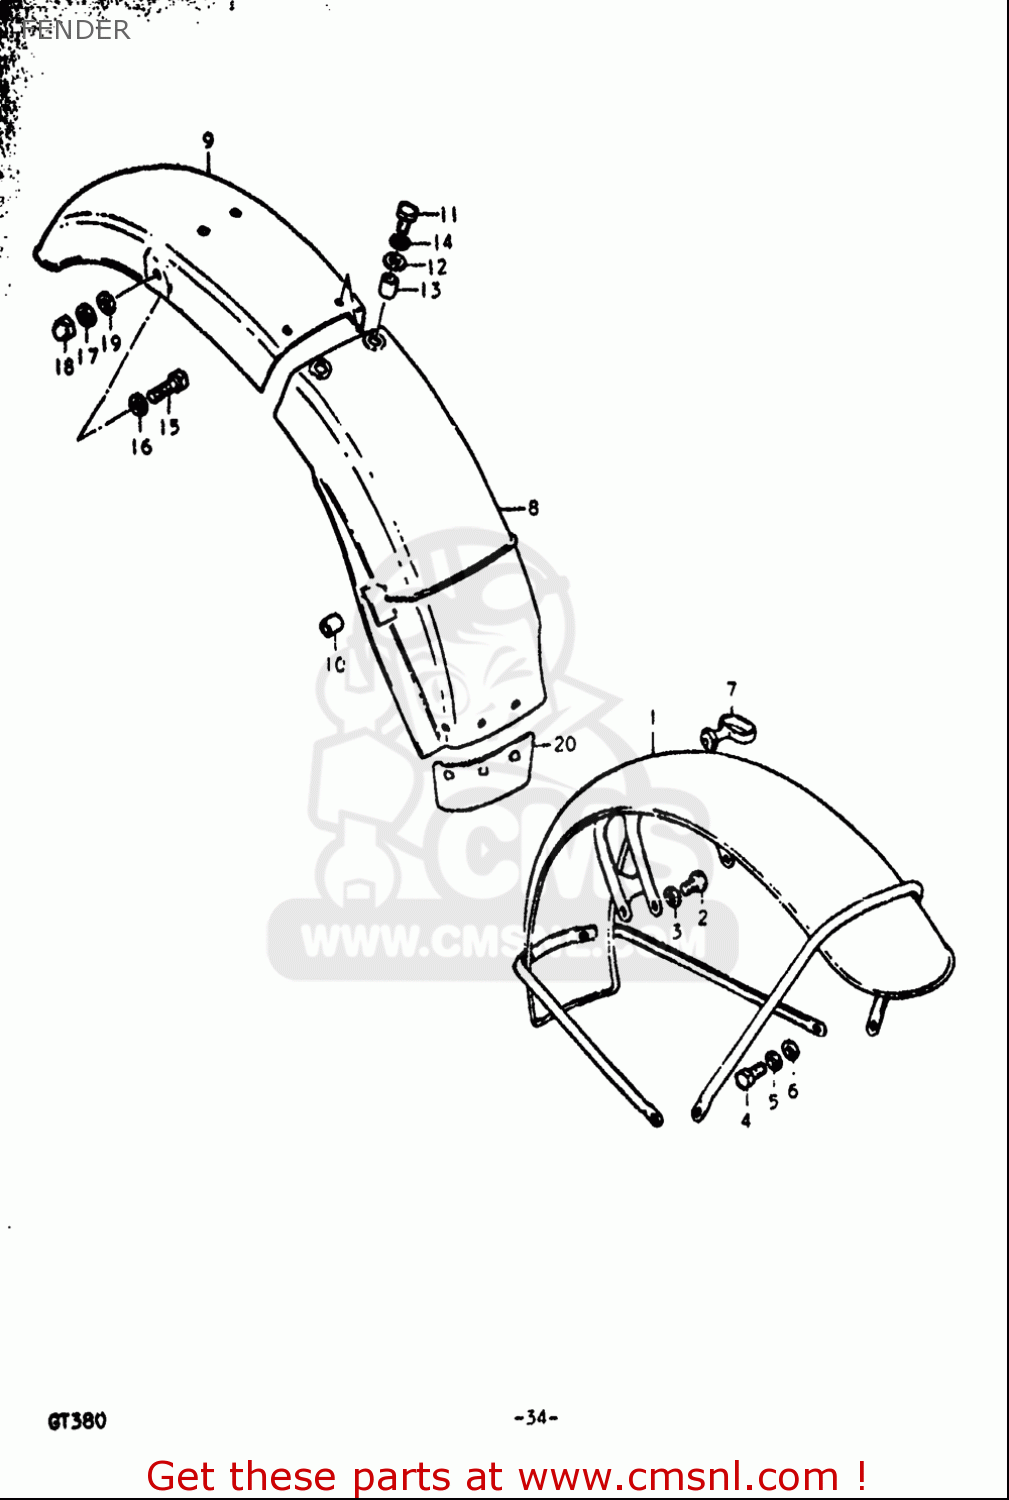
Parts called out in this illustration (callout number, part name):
2	BOLT
3	WASHER,LOCK
4	BOLT
5	WASHER
6	WASHER,LOCK
7	GUIDE,CABLE
10	CUSHION
11	BOLT
12	WASHER
13	SPACER
14	WASHER,LOCK
15	BOLT
16	WASHER
17	WASHER,LOCK
18	NUT
